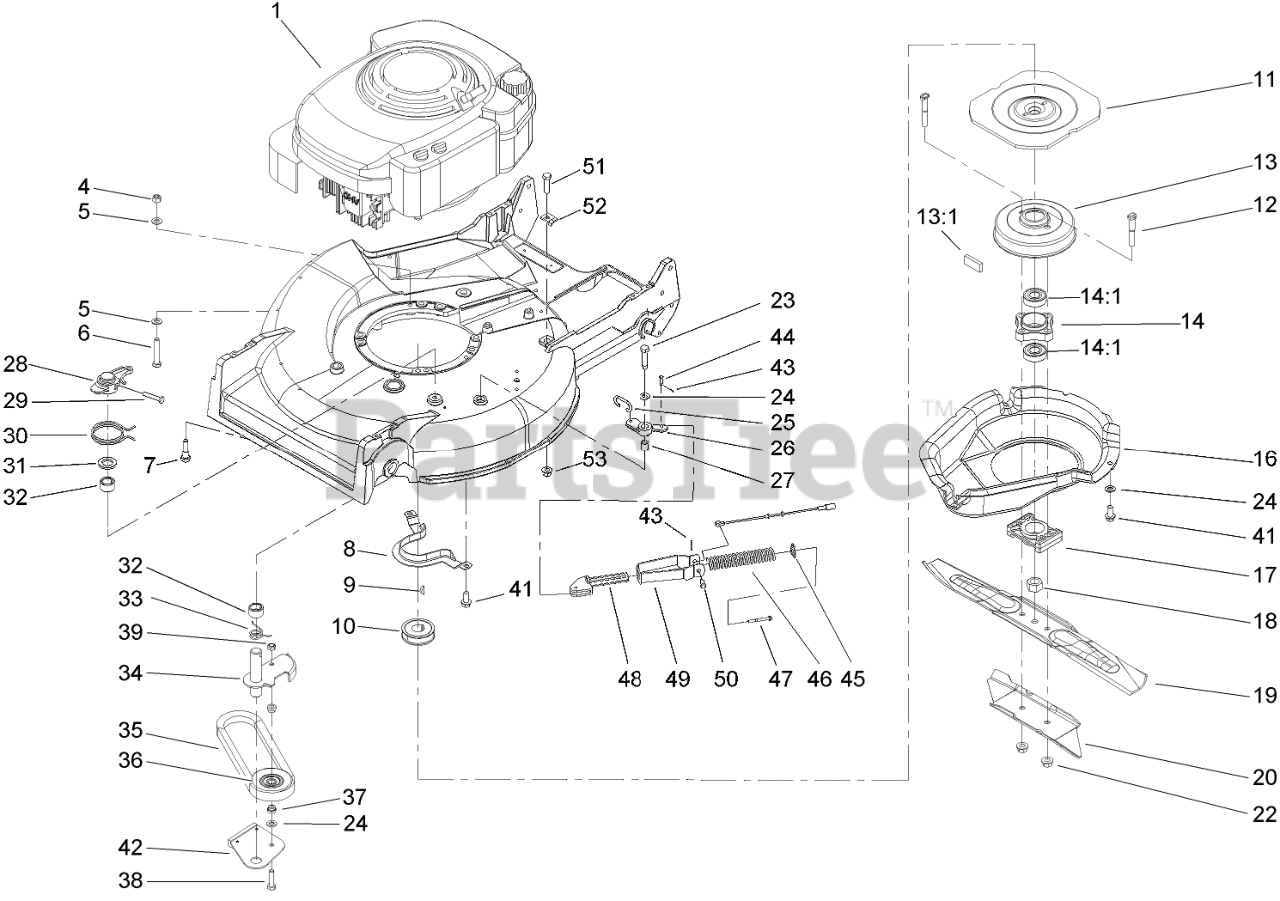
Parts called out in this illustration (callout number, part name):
4	NUT-LOCK, NI
5	WASHER-PLAIN
6	SCREW-HH
7	SCREW-SHOULDER
8	BRACKET-GUIDE, BELT
9	KEY-WOODRUFF
10	PULLEY-DRIVER
11	FLYWHEEL-BBC
12	BOLT-BLADE
13	BRAKE DRUM ASM
13:1	DAMPENER-VIBRATION
14	HUB ASM
14:1	BEARING-BALL
16	SHIELD
17	SPACER-BLADE
18	NUT-BLADE
19	BLADE-21 INCH
20	STIFFENER-BLADE
22	NUT-LOCK
23	SCREW-HH
24	WASHER-PLAIN
25	LINK-CONTROL
26	BELLCRANK
27	SLEEVE-BELLCRANK
28	LEVER
29	SCREW-HH
30	SPRING-TORSION
31	WASHER
32	BEARING
33	SPRING-TORSION
34	ARM-IDLER
35	V-BELT
36	PULLEY-IDLER
37	SPACER-PULLEY, IDLER
38	SCREW-HH
39	NUT-LOCK, NI
41	SCREW-HWHTF
42	BRAKE PLATE ASM
43	PIN-COTTER
44	PIN-SPRING
45	RETAINER-SPRING
46	SPRING
47	SCREW-HWHTF
48	GUIDE-SPRING
49	BRACKET-SPRING
50	PIN-CABLE
51	SCREW-HH
52	CLAMP-CABLE
53	NUT-LOCK, NI
